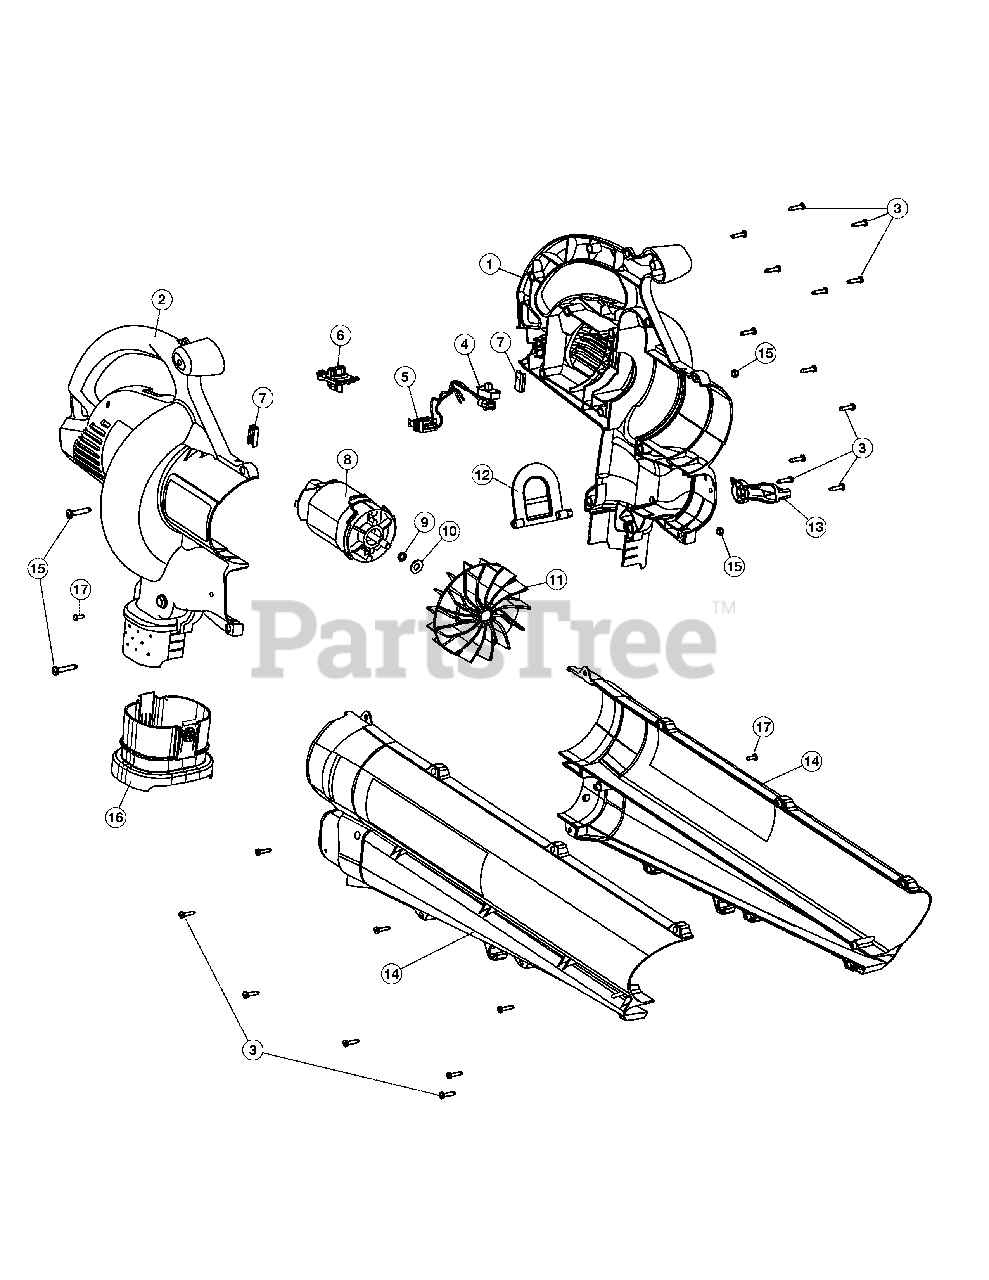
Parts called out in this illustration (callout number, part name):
1	Left Motor Housing
2	Right Motor Housing
3	Housing Screw
4	Switch Assembly
5	Power Connection Wire Assembly
6	Switch Lever
7	Rubber Cushion
8	Motor Assembly
11	Impeller
12	Mode Control Flapper
13	Mode Control Lever
14	Blower/Vac Tube Assembly
15	Blower/Vac Tube Mounting Hardware
16	Vacuum Bag Adapter
